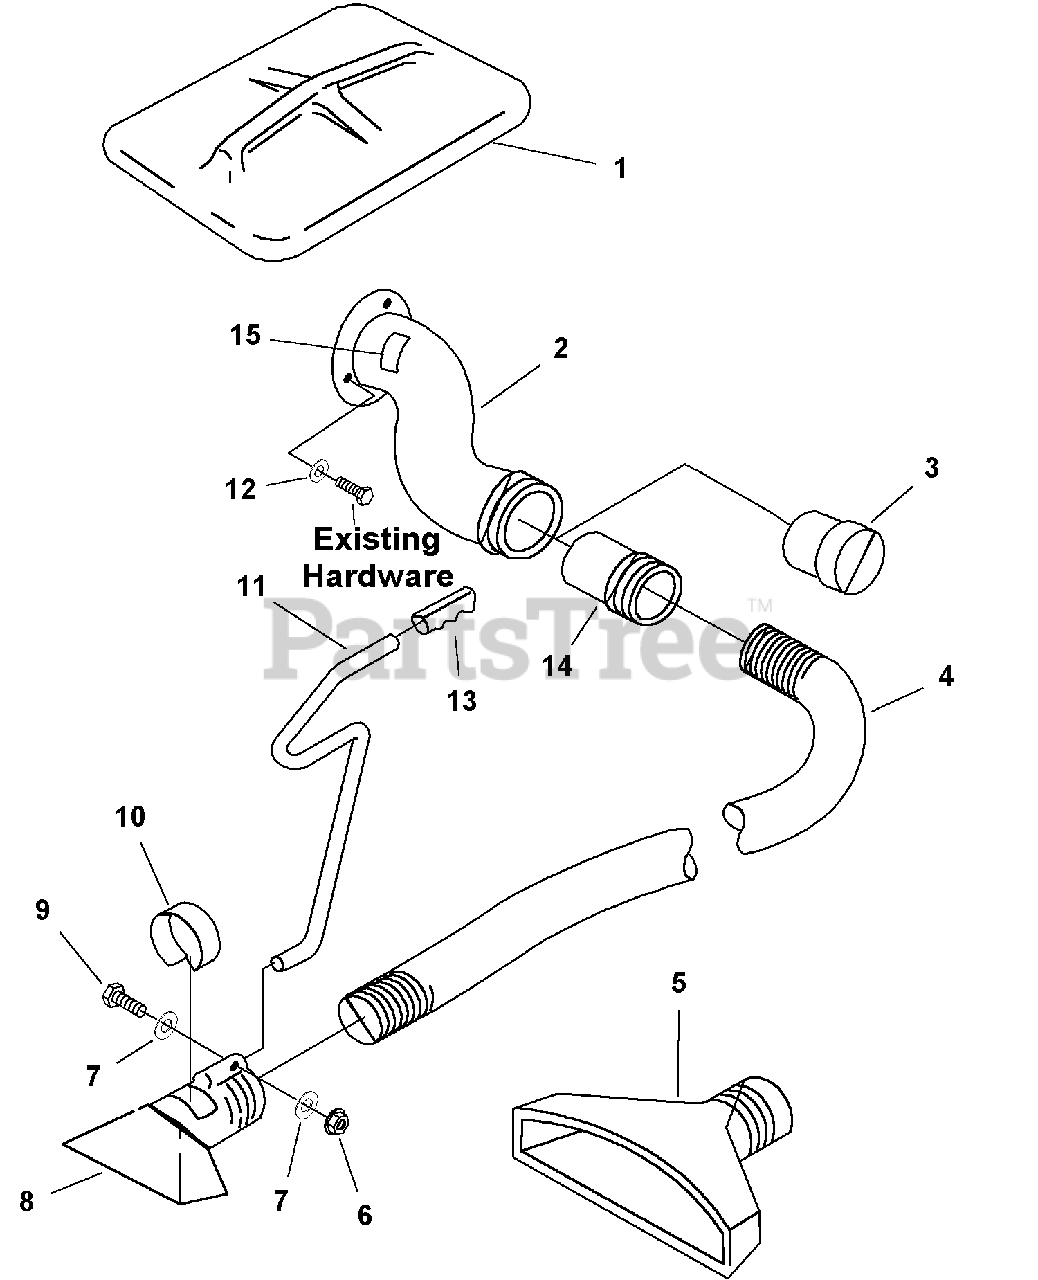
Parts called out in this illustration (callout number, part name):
6	NUT, Whizlock, 1/4-20
7	WASHER, 1/4
9	CAPSCREW, Truss Head, 1/4-20 x 1-1/2
11	HANDLE
12	WASHER, 5/16
15	DECAL, Danger Rotating Cutters
